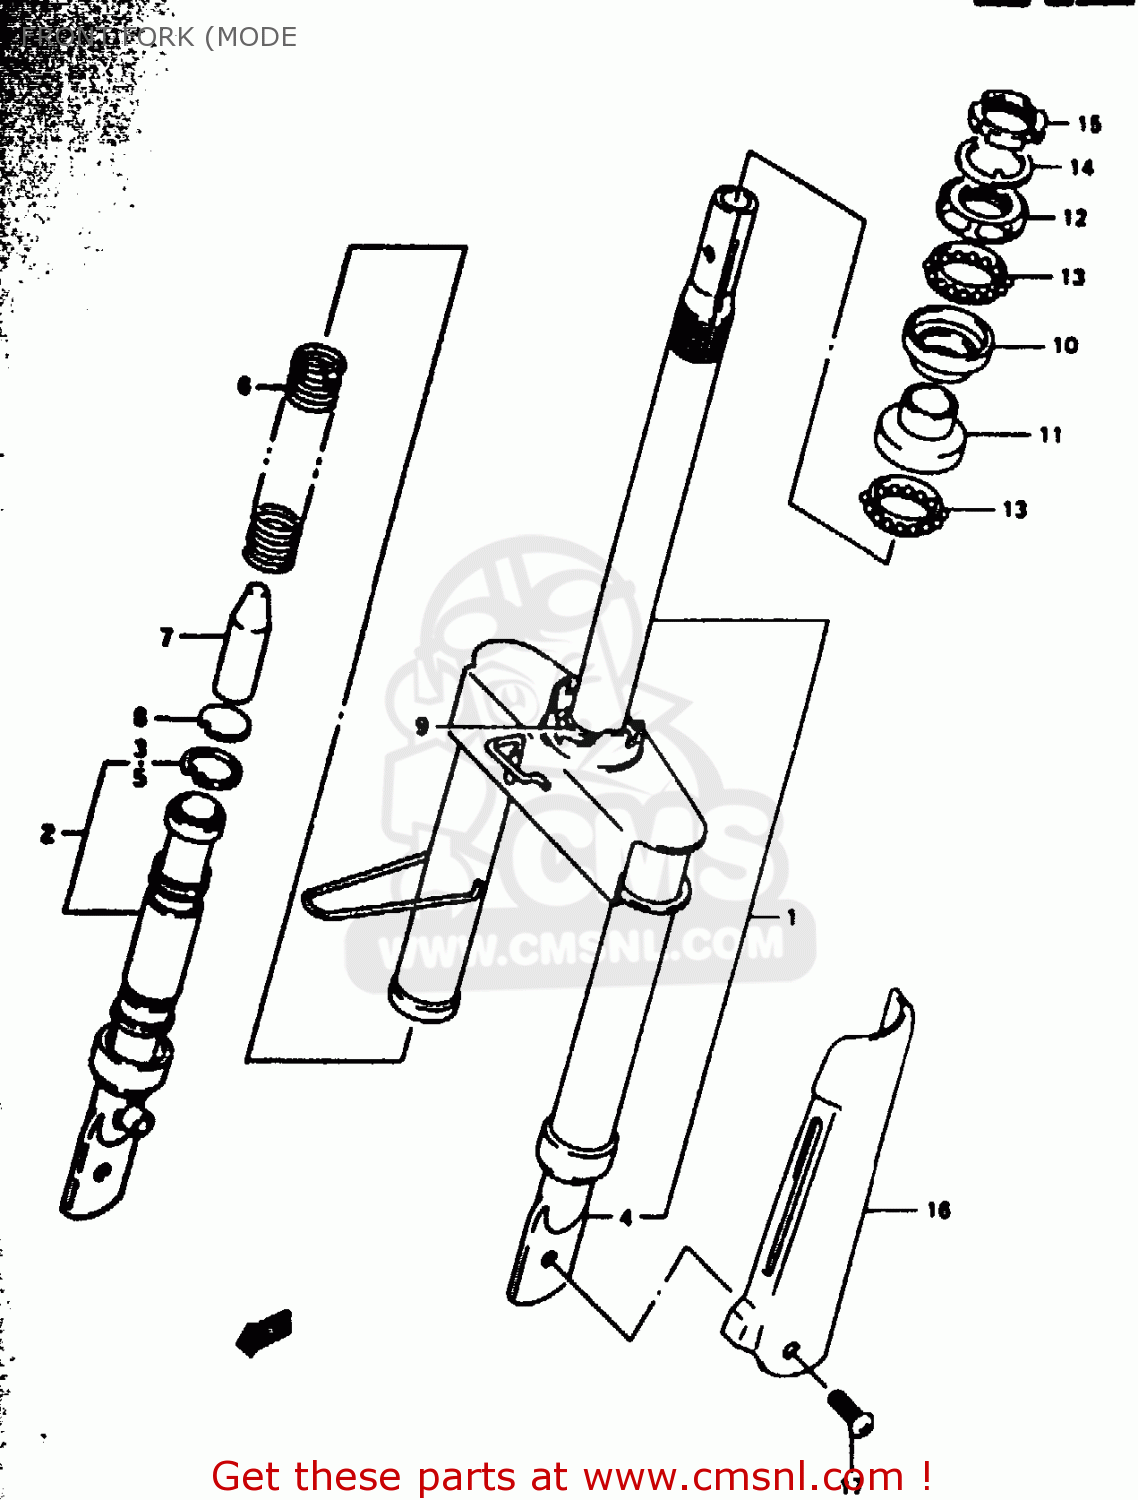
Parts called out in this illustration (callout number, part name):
1	FORK SET, FRONT (BLACK)
2	TUBE ASSY,FR FORK LWR,R
3	CIRCLIP
4	TUBE ASSY,FR FORK LWR,L
5	CIRCLIP
6	SPRING,FR FORK
7	STOPPER,RUBBER FR FORK
8	PLUG(OD:26)
9	RACE,STEERING,OUTER,LOWER
10	RACE,STEERING,INNER,UPPER
11	RACE,STEERING,INNER,LOWER
12	RACE,STEERING,OUTER,UPPER
13	BEARING(31.5X37X4.6)
14	WASHER
15	NUT
16	COVER,FR FORK
17	SCREW 6X12
18	SPACER (6.1X8X5.2)
